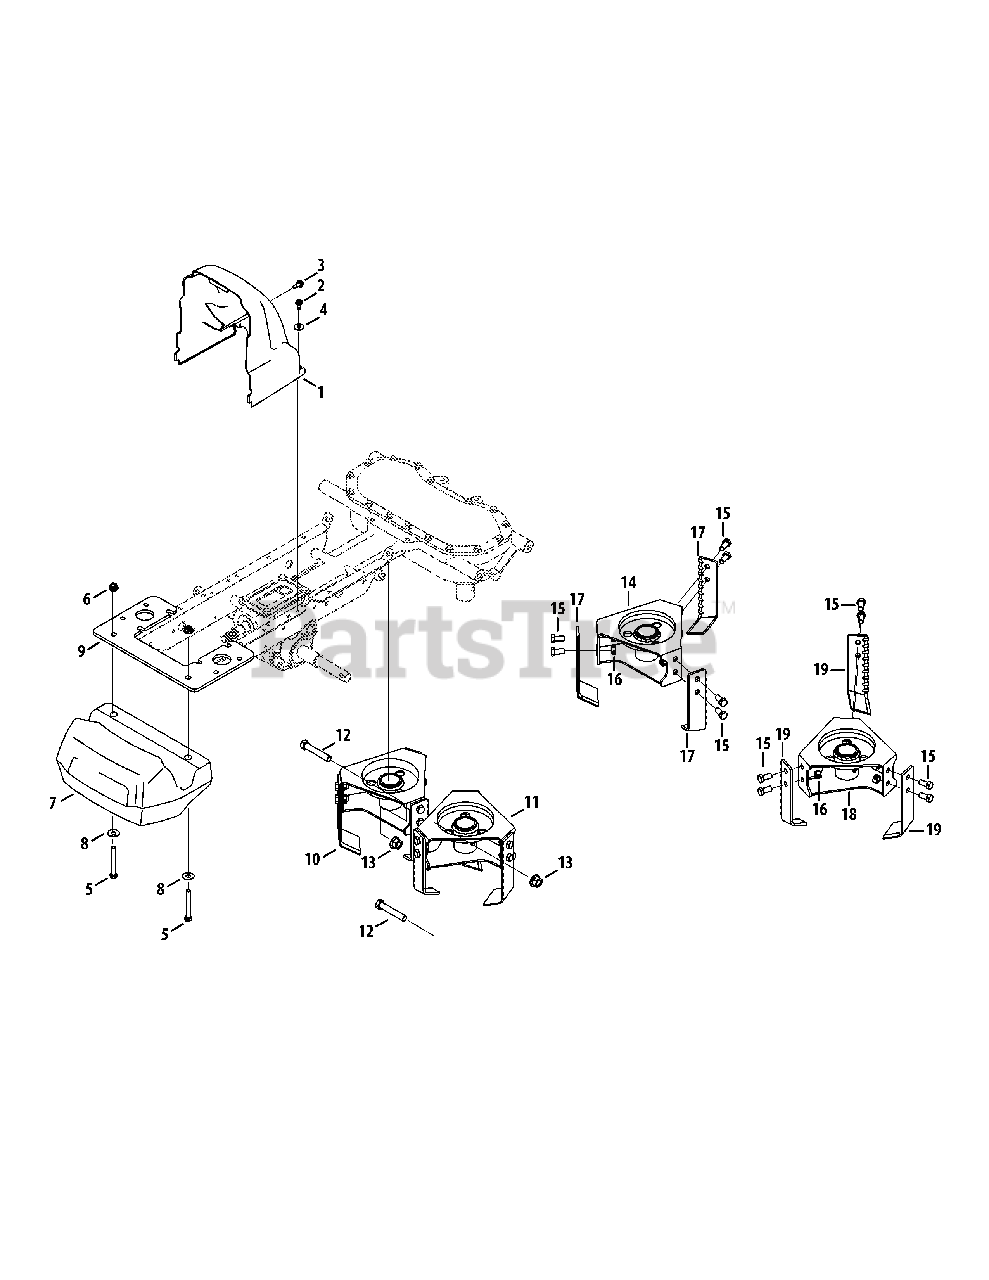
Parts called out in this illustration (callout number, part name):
1	Belt Cover
2	Screw, 1/4-20 x 0.500
3	Self Tapping Screw, 1/4-14 x .625
4	Washer, Flat, .28 x .74 x .063
5	Hex Screw, 5/16-18, 2.50, Gr5
6	Flangelock Nut, 5/16-18, B&S
8	Flat Washer, .349 x .879 x .063
9	Bumper Mounting Plate
10	Tine Assembly, RH
11	Tine Assembly, LH
12	Hex Cap Screw, 7/16-20 x 2.5 (Grade 5)
13	Flange Lock Nut, 7/16-20
14	Tine Bracket, RH
15	Hex Cap Screw, 3/8-16 x .75
16	Hex Lock Nut, 3/8-16
17	Tine Blade, RH
18	Tine Bracket, LH
19	Tine Blade, LH
